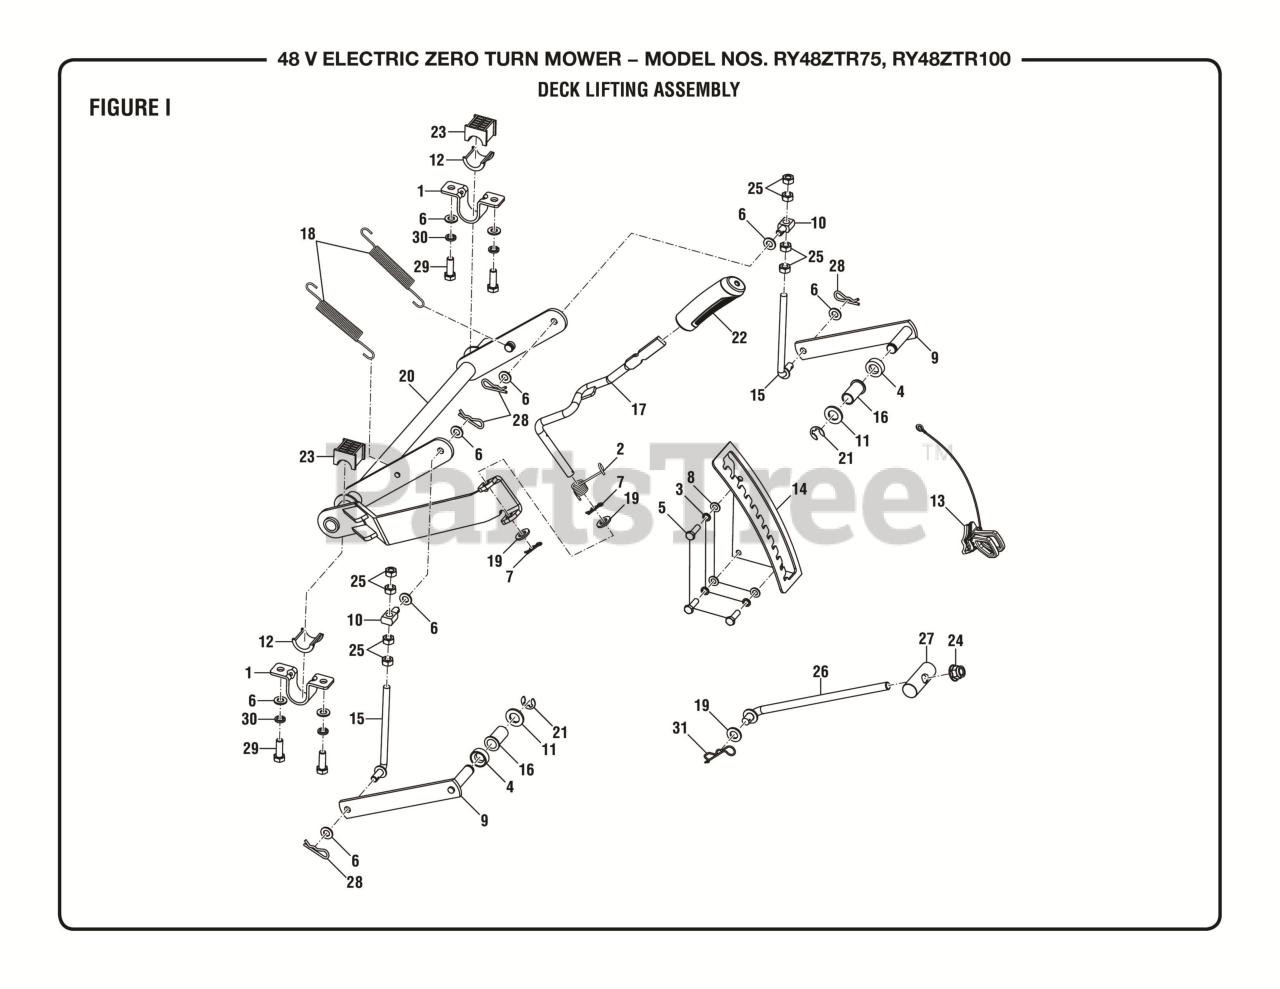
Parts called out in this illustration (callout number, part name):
1	Deck Lift Axle Mount
2	Deck Lift Lever Torsion Spring
3	Lock Washer (OD9.8 x ID8.5 x 5t)
4	Deck Lift Linkage Spacer
5	Bolt (M8 x 25 mm, Hex Hd.)
6	Washer (OD20 x ID10.5 x 2t)
7	Cotter Pin (12 mm)
8	Washer (OD16 x ID8.4 x 1.6t)
9	Deck Lift Linkage
10	Hanger Stud, ZTR
11	Washer (OD30 x ID17 x 3t)
12	Deck Lift Axle Bushing, Bottom
13	Cut Height Memory Plug
14	Detent Plate
15	J Hook, Deck Hanger
16	Deck Lift Linkage Bushing
17	Deck Lift Lever
18	Deck Lift Spring
19	Washer (OD24 x ID13 x 2.5t)
20	Deck Lift Linkage and Axle Assembly
21	E-Ring Clip (12 mm)
22	Decklift Handle
23	Deck Lift Axle Bushing,Top
24	Flange Nut (M12)
25	Nut (M10)
26	J Hook, Front Deck Hanger
27	Front Deck Hanger Pivot Axle
28	Cotter Pin
29	Hex Head (M10 x 30 mm)
30	Lock Washer (M10)
31	Hinge Cotter Pin
